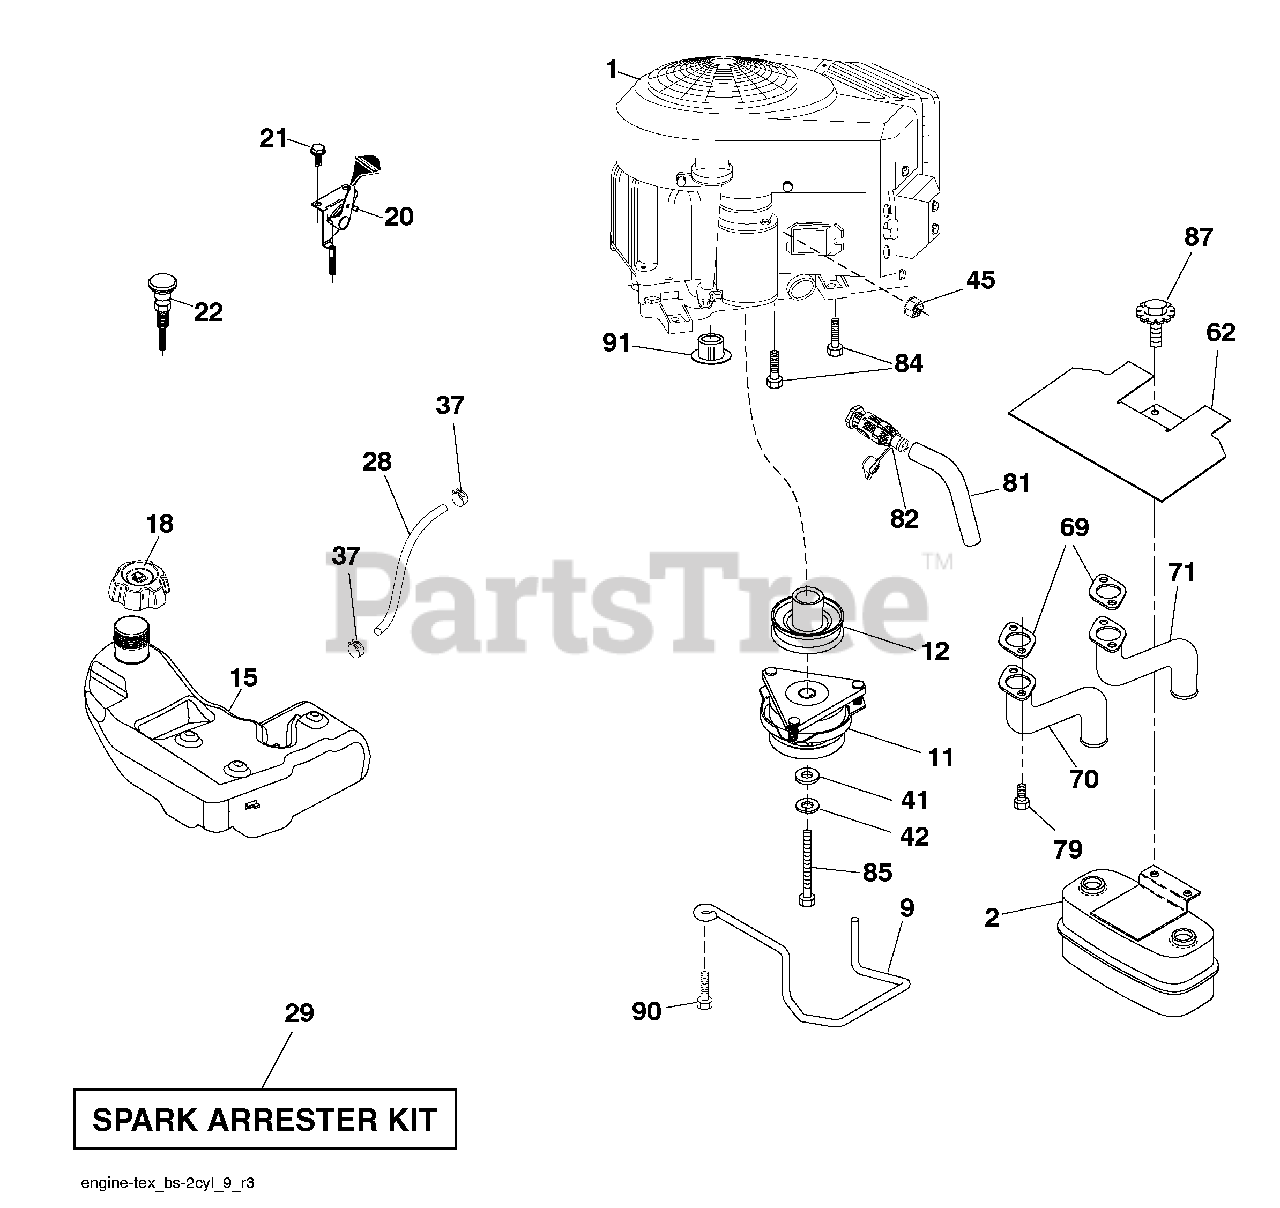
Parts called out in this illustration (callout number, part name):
2	Muffler
9	Keeper Belt Engine
11	Clutch Electric
12	Pulley Engine
15	Tank Fuel 4.0
18	Cap Asm Fuel
20	Control Throttle
21	Screw #10 x .750 BOS Thread
22	Control Choke
28	Fuel Line
29	Spark Arrester Kit
37	Clamp Hose
41	Washer 1-1/2 OD x 15/32 ID x .250
42	Washer Lock 7/16
45	Nut Keps Hex 1/4-20 unc
62	Shield Heat Muffler
69	Gasket
70	Tube Exhaust LH
71	Tube Exhaust RH
79	Screw Socket Head
81	Tube Drain Oil Easy
82	Valve Drain Oil
84	Screw 3/8-16 x 1-1/4
85	Bolt Hex 7/16-20 x 3.75 Gr. 5
87	Bolt 5/16-18 unc x 1 w/Sems
90	Screw 3/8-16 x 1
91	Bushing 1.375 OD
